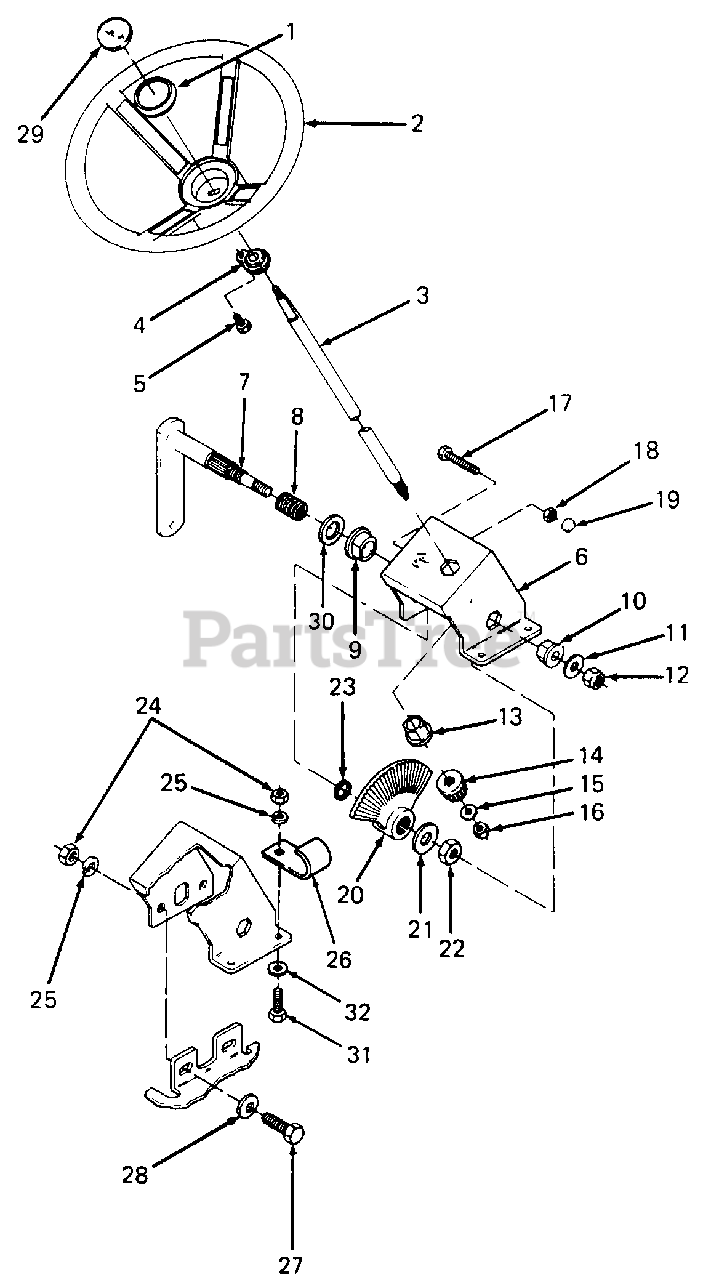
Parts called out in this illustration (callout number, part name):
1	Cap, Steering Wheel
2	Wheel, Steering
3	Shaft, Steering Wheel
4	Bearing, Steering Column
5	Screw, Oval Hd Cnt. Sunk, #10 X .62 Lg
6	Box, Steering
7	Shaft, Steering
8	Spring, Compression
9	Bearing, Flange
10	Bearing, Flange
11	Washer, Flat, .515 X 1.12 X .100 Thk HDN
12	Nut, Hex Center Lock, 1/2-13 GR5
13	Bearing, Flange
14	Gear, Pinion
15	Washer, Flat, .320 X .60 X .06 Thk HDN
16	Nut, Hex Center Lock, 5/16-24
17	Screw, Hex, 3/8-16 X 2.25 Lg GR5
18	Nut, Hex Jam, 3/8-16 GR5
20	Gear, Bevel
21	Washer, Flat, .640 X 1.25 X .06 Thk
22	Nut, Hex Jam, 5/8-18
23	Ring, Snap
24	Nut, Hex, 5/16-18 GR5
25	Washer, Lock, 5/16
26	Clip, Cable
27	Screw, Hex Cap, 5/16-18 X 1.0 Lg GR5
28	Washer, Bell, .345 X .88 X .060 Thk
29	Label, Steering Cap
30	Washer, Flat, .760 X 1.49 X .06 Thk HDN
31	Screw, Hex Cap, 5/16-18 X 1.25 Lg
32	Retainer, Bolt, 5/16-18
